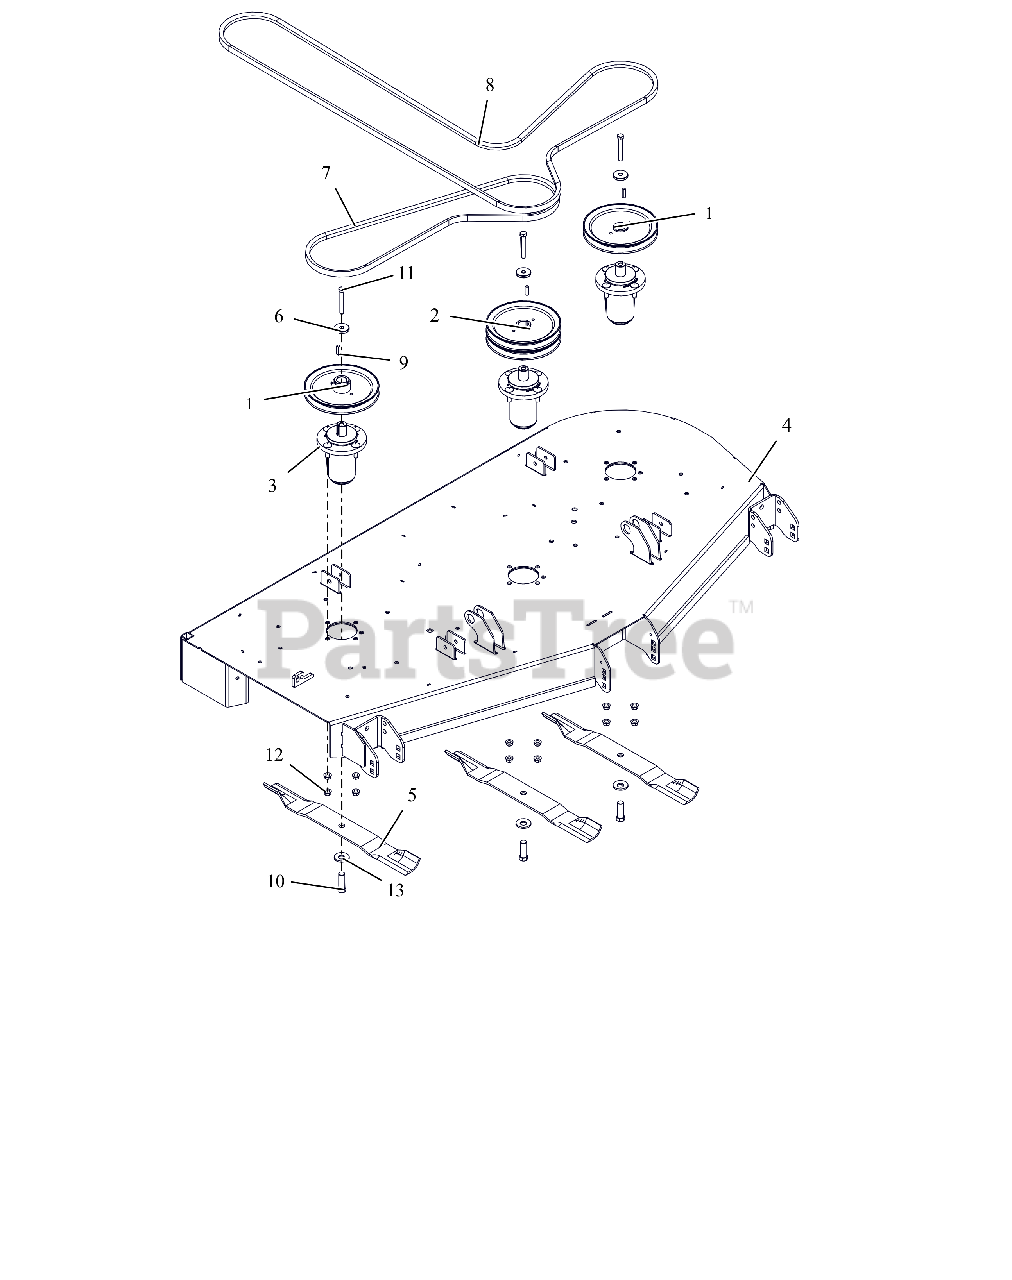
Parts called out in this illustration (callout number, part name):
1	PULLEY, V-7.50 OD X 1"ID
2	PULLEY, DOUBLE 1"X7.50"&7.50" (BLACK)
3	ASM, MAINT FREE ALUM SPINDLE
4	KIT,DECK-60" W/DECALS-GRAVELY
5	BLADE, 20.5"
6	RETAINER, SHEAVE
7	V-BELT, B-COGGED
8	V-BELT, HB SECTION
9	KEY, SQ .25X.25X1.00 RC 40-50
10	BLT, HEX .62-18X1.75 G8 ZCC
11	BLT, HEX .38-16X2.75 G8 ZCC
12	NUT-LK-CTR-FLG .375-16 GF ZCC
13	WSHR-BLVL .669X1.535X.138
